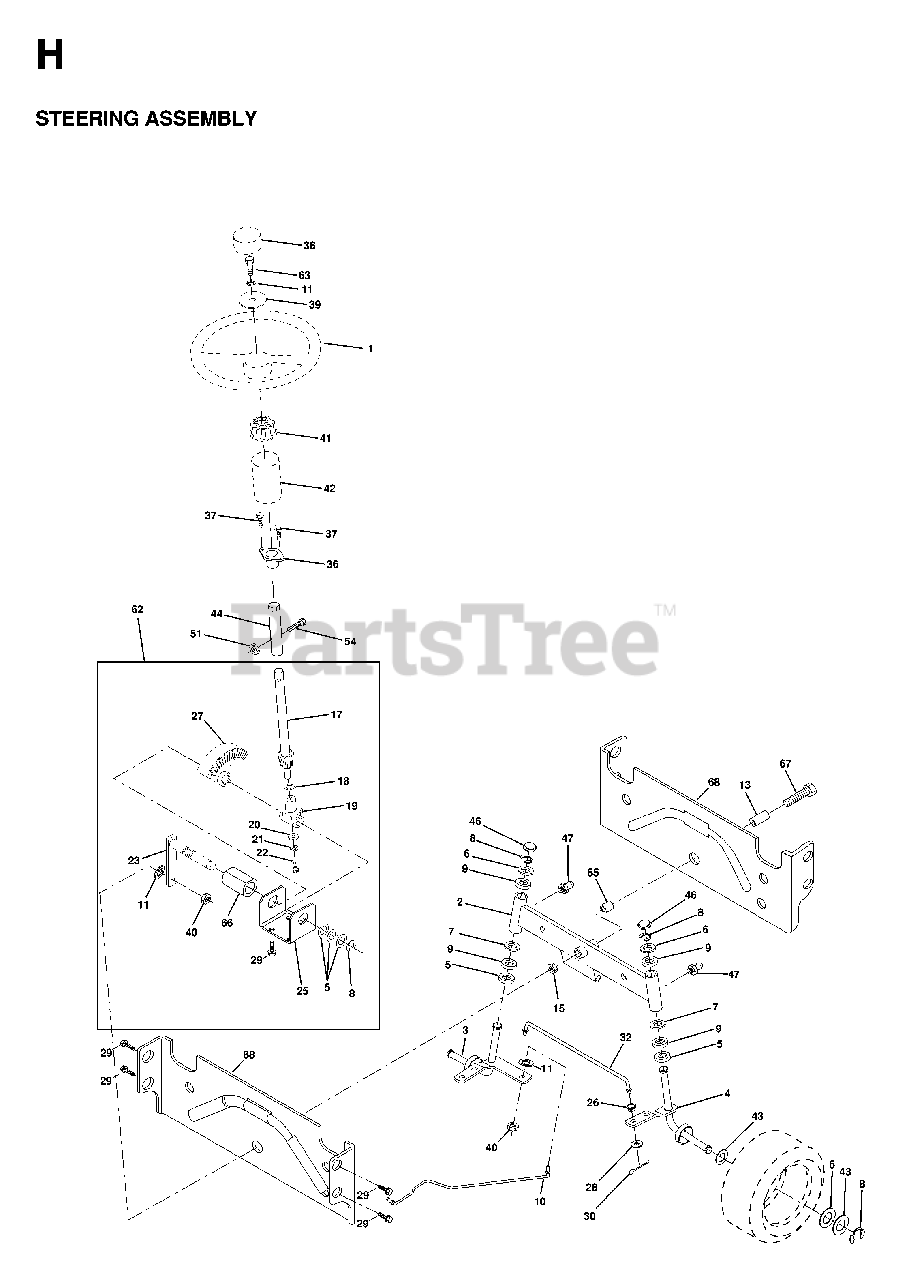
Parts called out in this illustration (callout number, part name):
2	AXLE ASSY
3	SPINDLE.ASM.LH
4	SPINDLE ASM, RH
8	RING CLIP
9	BRNG T
10	DRAGLINK-STAMPED
11	WASHER, LOCK 3/8
13	BEARING AXLE
15	NUT-LOC,FLANGE LT
17	SHAFT ASM STEERING
18	THRUST WASHER
19	SHAFT,SUPPORT
20	WASHER
21	LOCKWASHER
22	SCREW
23	PITMAN SHAFT ASSY
25	BRACKET STEERING
26	BUSHING.DRAGLINK
27	GEAR.SECTOR
28	WASHER
29	SCREW
30	COTTER PIN
32	TIE ROD
36	BUSHING, STEERING
38	RP INSERT
39	WASHER T
40	GRIPCO NUT
41	ADAPTER LT
42	STEERING BOOT, GRAY
44	EXT SHAFT STEERING
46	CAP.SPINDLE
47	ZERK M
51	NUT.71038.31-18.HEX.NYLOCK
54	BOLT.5/16-18X1-1/4 FULL.THREAD
62	KIT, STEERING ASSEMBLY
65	SPACER AXLE
66	BEARING ARM
67	BOLT.HEX.FINISHED.5/8
